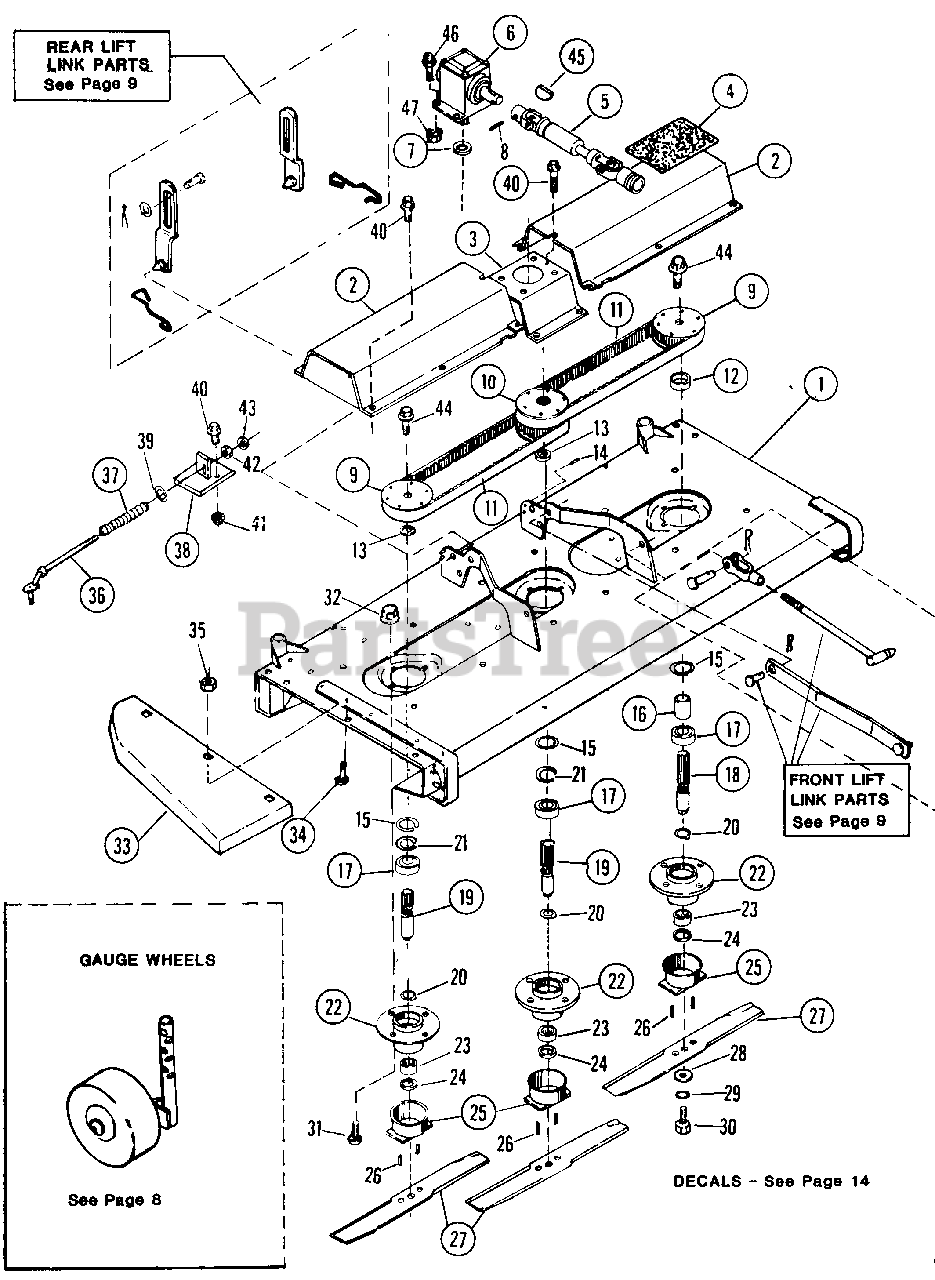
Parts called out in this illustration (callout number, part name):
1	(NLA) MOWER HOUSING WELDMENT
2	(NLA) COVER, TIMING BELT (RIGHT & LEFT SIDE)
3	(NLA) SUPPORT, GEAR BOX
4	(NLA) TREAD, STEP
5	UNIVERSAL - JOINT ASSEMBLY
6	GEAR-BOX ASSEMBLY
7	SPACER, SPLINED
8	(NLA) PIN, GROOVE 1/4 x 1-3/4
9	PULLEY, TIMING BELT (RIGHT & LEFT SIDE)
10	PULLEY, TIMING BELT CENTER
11	BELT, DECK BLADE TIMING
12	SPACER, LEFT SIDE PULLEY
13	SPACER, RIGHT SIDE & CENTER PULLEY
14	PIN, HOUSING SPIROL
15	RING, RETAINING
16	SPACER, LEFT SIDE PULLEY (LOWER)
17	BEARING, BALL, .98" ID, 2.04" OD, .59" Wide
18	SHAFT, LEFT SIDE SPINDLE (6" LONG)
19	SHAFT, CENTER & RIGHT SIDE SPINDLE (4-3/4" LONG)
20	RING, RETAINING
21	RING, RETAINING
22	HOUSING, SPINDLE
23	(NLA) BEARING, NEEDLE
24	SEAL, OIL
25	MOUNTING, CUTTING BLADE
26	PIN, BLADE MOUNTING (SHEAR)
27	BLADE, MOWER CUTTING, 16.25"
28	WASHER, BLADE TO SPINDLE CONE
29	WASHER, 1/2 SPLIT LOCK
30	BOLT, 1/2C X 1-1/4 HEX HEAD
31	BOLT, 3/8C x 1-1/8 CARRIAGE
32	NUT, 3/8C HEX FLANGE LOCK
33	CHUTE, MOWER SIDE DISCHARGE
34	BOLT, 1/4C x 3/8 CARRIAGE
35	NUT, 1/4C HEX FLANGE LOCK
36	ROD, BELT ADJUSTING
37	SPRING, BELT ADJUSTER
38	BRACKET, BELT ADJUSTING
39	WASHER, 3/8" Flat
40	BOLT, 5/16C x 3/4 HEX FLANGE LOCK
41	NUT, 5/16C HEX FLANGE LOCK
42	NUT, 3/8C HEX
43	NUT, 3/8C HALF HEX
44	BOLT, 3/8C x 1 HEX FLANGE LOCK
45	KEY, WOODRUFF
46	BOLT, 3/8-16 x 1-1/4 HEX HEAD
47	NUT, 3/8-16 HEX FLANGE LOCK
